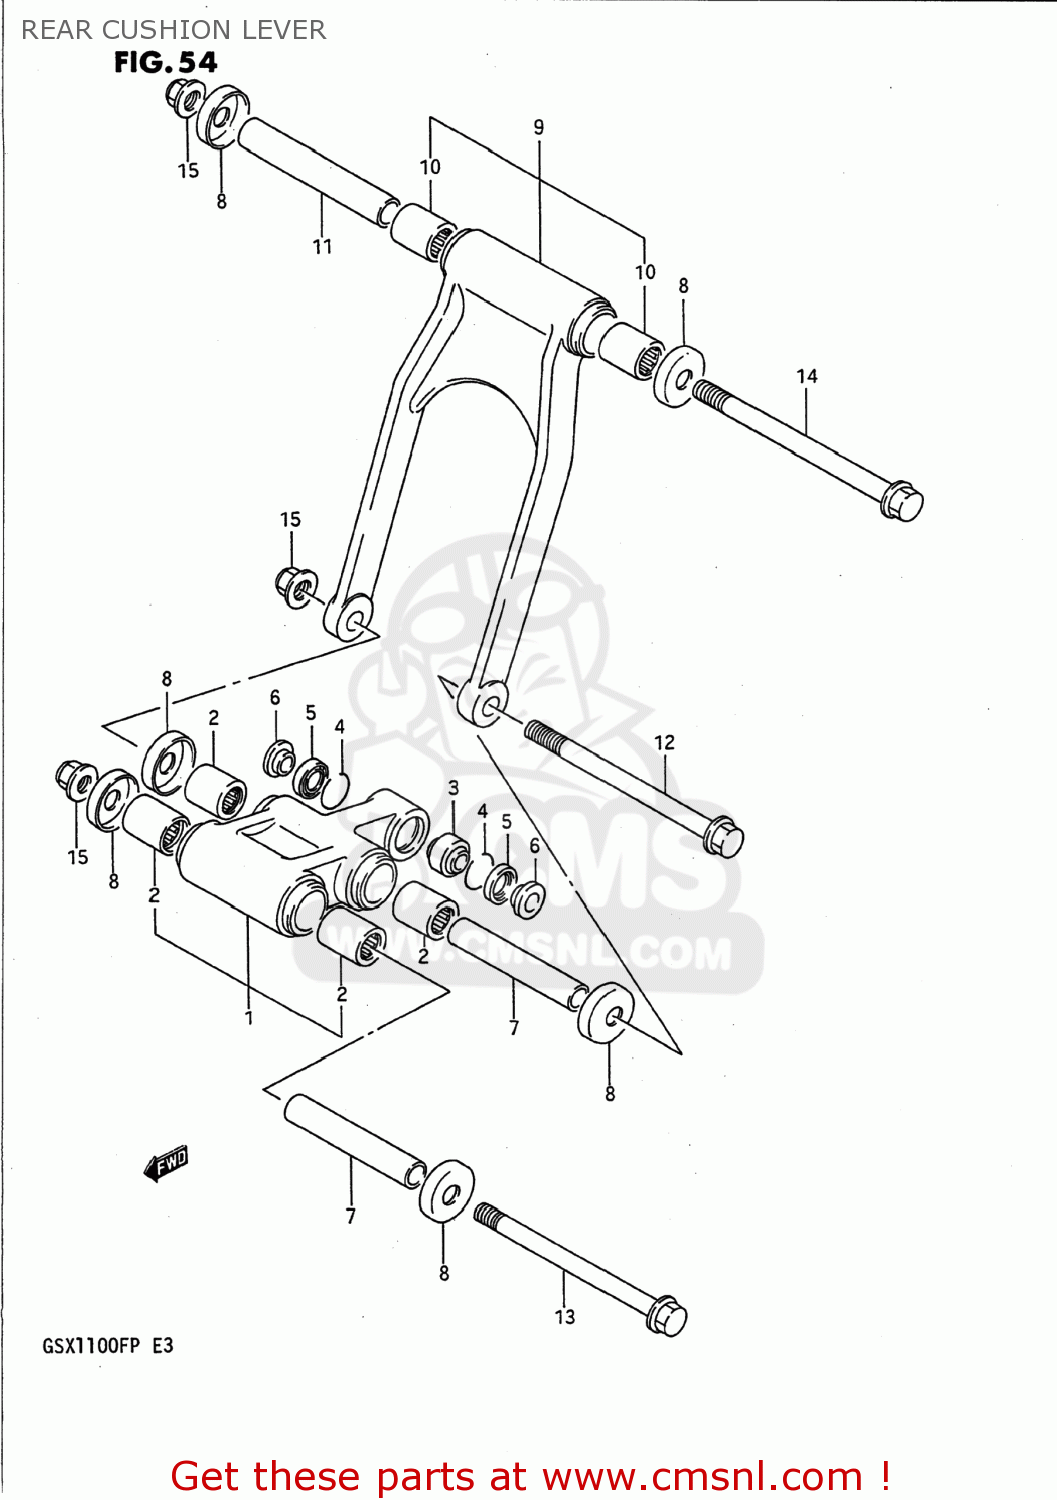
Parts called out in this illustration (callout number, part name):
1	LEVER SET,REAR CUSHION
2	BEARING(17X24X30)
3	BEARING,RR CUSHION LEVER
4	RING,STOPPER
5	DUST SEAL,RR CUSHION LEVER RR
6	SPACER
7	SPACER,REAR CUSHION LEVER
8	COVER,THRUST
9	ROD SET,REAR CUSHION,LEFT
10	BEARING(17X24X30)
11	SPACER,REAR CUSHION ROD
12	BOLT L:145
13	BOLT L:135
14	BOLT(12X155)
15	NUT 12MM
